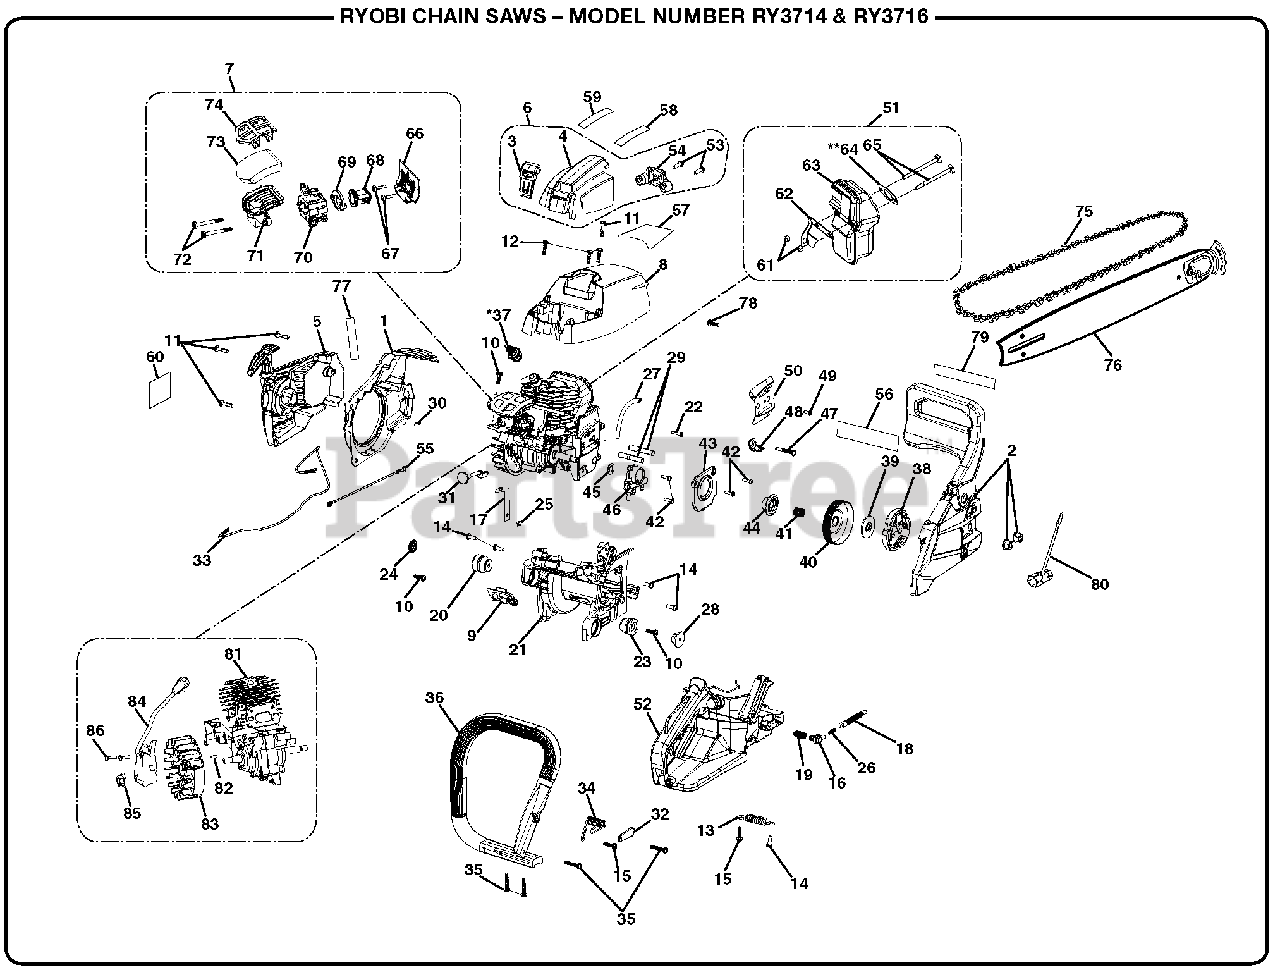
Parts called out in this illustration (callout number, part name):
1	Cylinder Baffle
2	Clutch Cover Assembly
3	Carburetor Cover Latch and Bracket Assembly
4	Carburetor Cover Housing
5	Starter Housing Assembly
6	Carburetor Cover Assembly
7	Intake Assembly
8	Cylinder Housing Assembly
9	Throttle Rod Grommet
10	Screw (M5 x 16 mm, T25 Torx Pan Hd.)
11	Screw, Truss Hd., Plastite (10-14 x 7/8")
12	Screw (M5 x 14 mm, T25 Torx Pan Hd.)
13	Damper Spring
14	Screw (M5 x 0.8 mm, T25 Torx Pan Hd.)
15	Screw (M5 x 14 mm, T25 Torx Pan Hd.)
16	Oil Filter Grommet
17	Band Stopper
18	Rubber, Pipe In Oil Pump
19	Cone Spring
20	Rubber Damper
21	Engine Case
22	Pin (Oil Pump Outlet)
23	Damper Rubber
24	Damper Cap.
25	Starter Case
26	Joint For Pipe In Comp
27	Oil Pump Rubber Tube (Outlet)
28	Damper Cap (T)
29	Bar Stud (5/16-18 x 23.5 mm / 5/16-18 x 18 mm)
30	Spring Clip (Choke Rod)
31	Choke Rod
32	Damper Plate
33	Lead Wire Assembly (Red)
34	Damper Spring
35	Screw (M5 x 27 mm, T25 Torx Pan Hd.)
36	Front Handle
37	Spark Plug (Bosch WSR6F)
38	Clutch Assembly
39	Thrust Plate
40	Clutch Drum
41	Clutch Drum Needle Bearing
42	Screw (M4 x 14 mm, T20 Torx Pan Hd.)
43	Oil Pump Cover
44	Oil Pump Drive Gear
45	Washer (Oil Pump Drive Gear)
47	Screw (M4 x 33 mm, T25 Torx Pan Hd.)
48	Chain Catcher.
49	Screw (M4 x 12 mm, T20 Torx Pan Hd.)
50	Chain Guard Plate.
51	Exhaust Assembly.
52	Chassis & Handle Components
53	Screw (M4 x 10 mm, T20 Torx Pan Hd.)
54	Screw (M4 x 14 mm, T20 Torx Pan Hd.)
55	Lead Wire Assembly (Black)
56	Chain Brake Label (RY3714)
56	Chain Brake Label (RY3716)
57	Warning Label
58	Starting Label (Right)
59	Starting Label (Left)
60	Starting House Label (RY3818)
61	Hex Nut (M5, Muffler)
62	Muffler Bracket
64	Gasket (Muffler).
65	Screw (M5 x 0.8 mm, T25 Torx Pan Hd.)
67	Bolt (M9 x 19 mm, T25 Torx Pan Hd.)
68	Intake Boot
69	Intake Bracket
70	Carburetor Assembly
71	Air Box Base
72	Screw (M5 x 44 mm,T25 Torx Hd. Carburetor)
73	Foam Air Filter
74	Air Filter Retainer
75	14 in. Chain (RY3714, 52 Drive Link)
75	16 in. Chain (RY3716, 56 Drive Link)
76	14 in. Guide Bar Assembly (RY3714)
76	16 in. Guide Bar Assembly (RY3716)
77	Warning Label (Combustion)
78	Screw (M5 x 11 mm., T25 Torx Pan Hd.)
79	Pull To Release Brake Label
80	Combination Wrench
81	Short Block
82	WOODRUFF KEY (10 mm X 3 mm)
83	Flywheel Assembly
84	Ignition Assembly
85	Flange Nut (M8, Flywheel)
